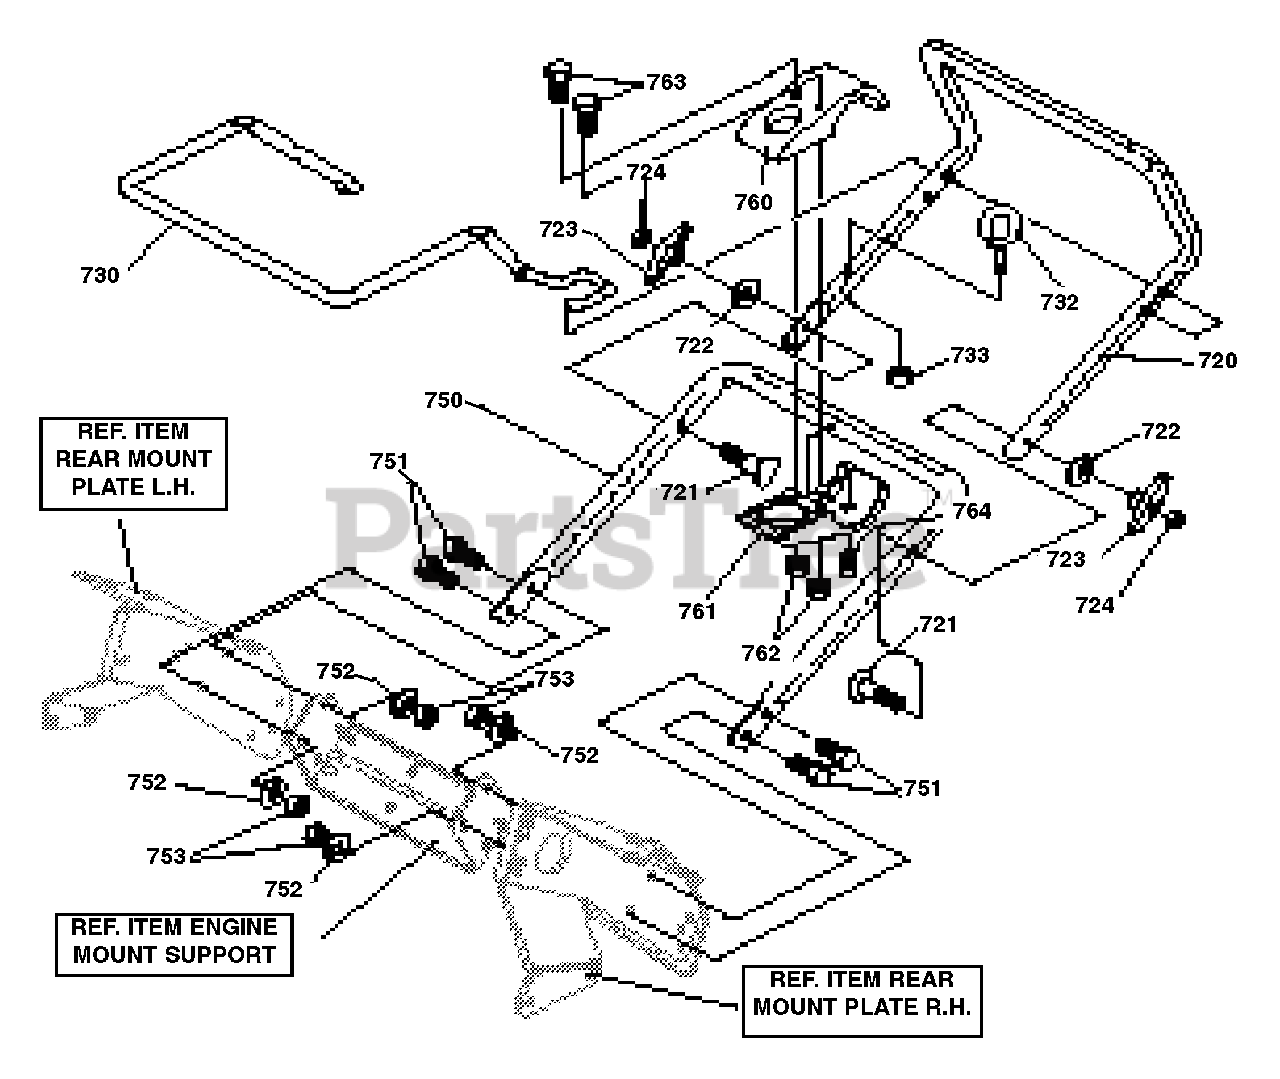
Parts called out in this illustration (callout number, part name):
720	HANDLE, ASSY
721	BOLT, 5/16-18 X 2.00
722	WASHER, FORM
723	KNOB, T
724	NUT, 5/16-18 REGHEX
730	BAR, CONTROL DRIVE
732	GUIDE, ROPE 5/15-18
733	NUT, 5/16-18 REGHEXCTRLK
750	HANDLE, LOWER
751	SCREW, 5/16-18 X .75
752	WASHER, FLAT .344 X .69 X.065
753	NUT, 5/16-18 REGHEXCTRLK
760	BRACKET HALF, CHUTE CRANK
761	BRACKET HALF, CHUTE CRANK
762	NUT, #10-24 HEXNYLLK
763	SCREW, #10-24 X 1.00
764	SCREW, 1/4-20 X .63
